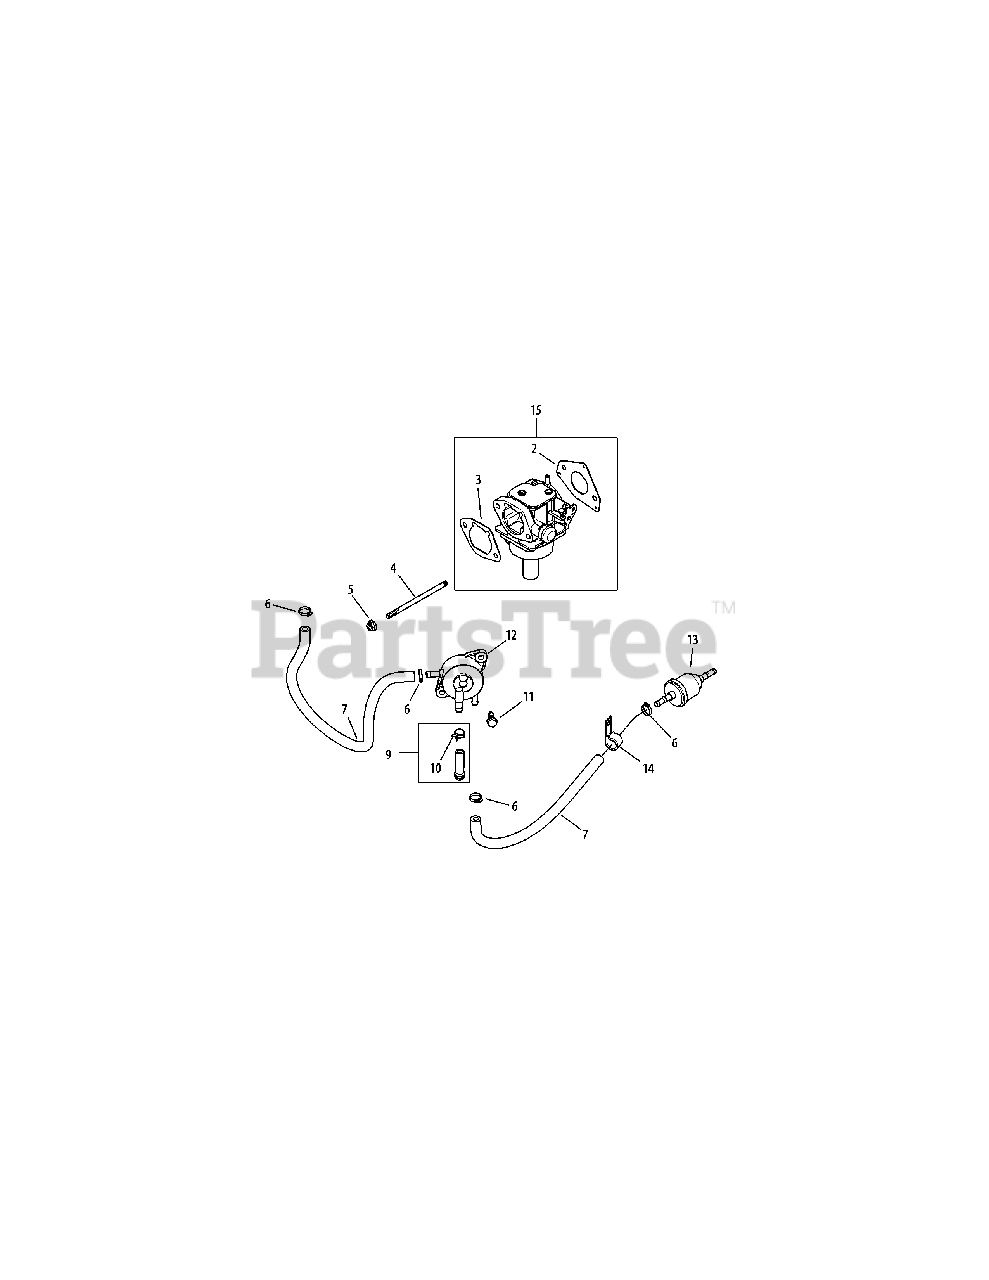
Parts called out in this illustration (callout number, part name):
2	Carburetor Gasket
3	Air Cleaner Base Gasket
4	Stud, M6 X 1.0 X 106
5	Flg. Nut, M6 X 1.0
6	Hose Clamp, 1/2
7	Fuel Line
11	Tap Screw, M6 X 1.7 X 18
15	Carburetor Kit (Inc. 2 & 3)
